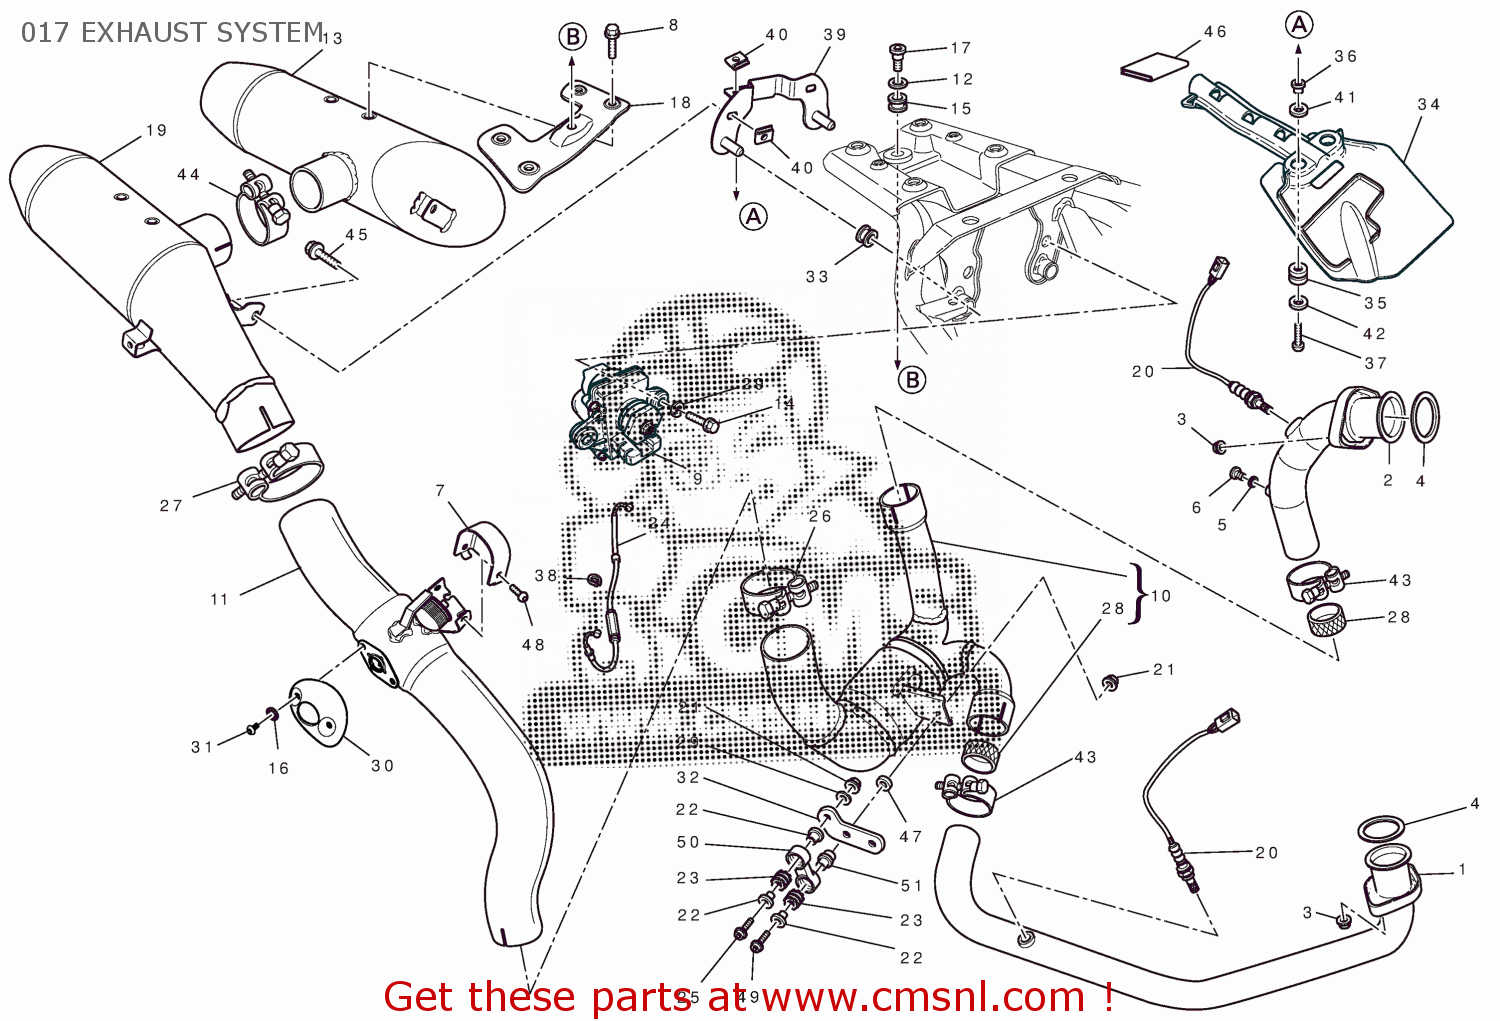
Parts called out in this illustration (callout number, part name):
1	HORIZONTAL EXHAUST PIPE
2	VERTICAL EXHAUST PIPE
3	NUT M8
4	GASKET, EXHAUST PIPE
5	WASHER 10X14X1
6	PLUG ASSY
7	GUARD
8	SCREW TEF M8X15
9	ELECTRIC MOTOR, EXHAUST VALVE
10	UNION
11	EXHAUSRT PIPE ASSY
12	WASHER 28X12.2X0.5
13	LEFT SILENCER
14	SCREW TEF M6X30
15	DAMPER
16	WASHER, SPRING
17	SCREW
18	BRACKET, SILENCER
19	RIGHT SILENCER
20	SENSOR LAMBDA SOND
21	NUT
22	SPACER 6.25X10X5.75
23	VIBRATION DAMPER PAD
24	CABLE, EXHAUST VALVE CLOSE
25	SCREW TCEIF
26	SILENCER CLAMP
27	SILENCER CLAMP
28	GASKET, MUFFLER
29	WASHER 6.4X14X1.2
30	GUARD, EXHAUST VALVE
31	SCREW TBEI M5X8
32	BRACKET
33	RUBBER PAD
34	MUDFLAP
35	DAMPER
36	SPACER 6.5X9.5X14
37	SCREW TBEI M6X30
38	CIRCLIP E-TYPE
39	BRACKET ACTUATOR EXHAUST CONTROL
40	QUICK FASTENING
41	WASHER 10.25X20X3
42	WASHER 6.2X20X1.5
43	CLAMP 49-20 MM
44	CLAMP 61-20 MM
45	SCREW TEF M6X12
46	VIBRATION DAMPER
47	SPACER
48	SCREW TBEI M6X8
49	SCREW TCEIF M6X35
50	BRACKET, SILENCER
51	SPACER
